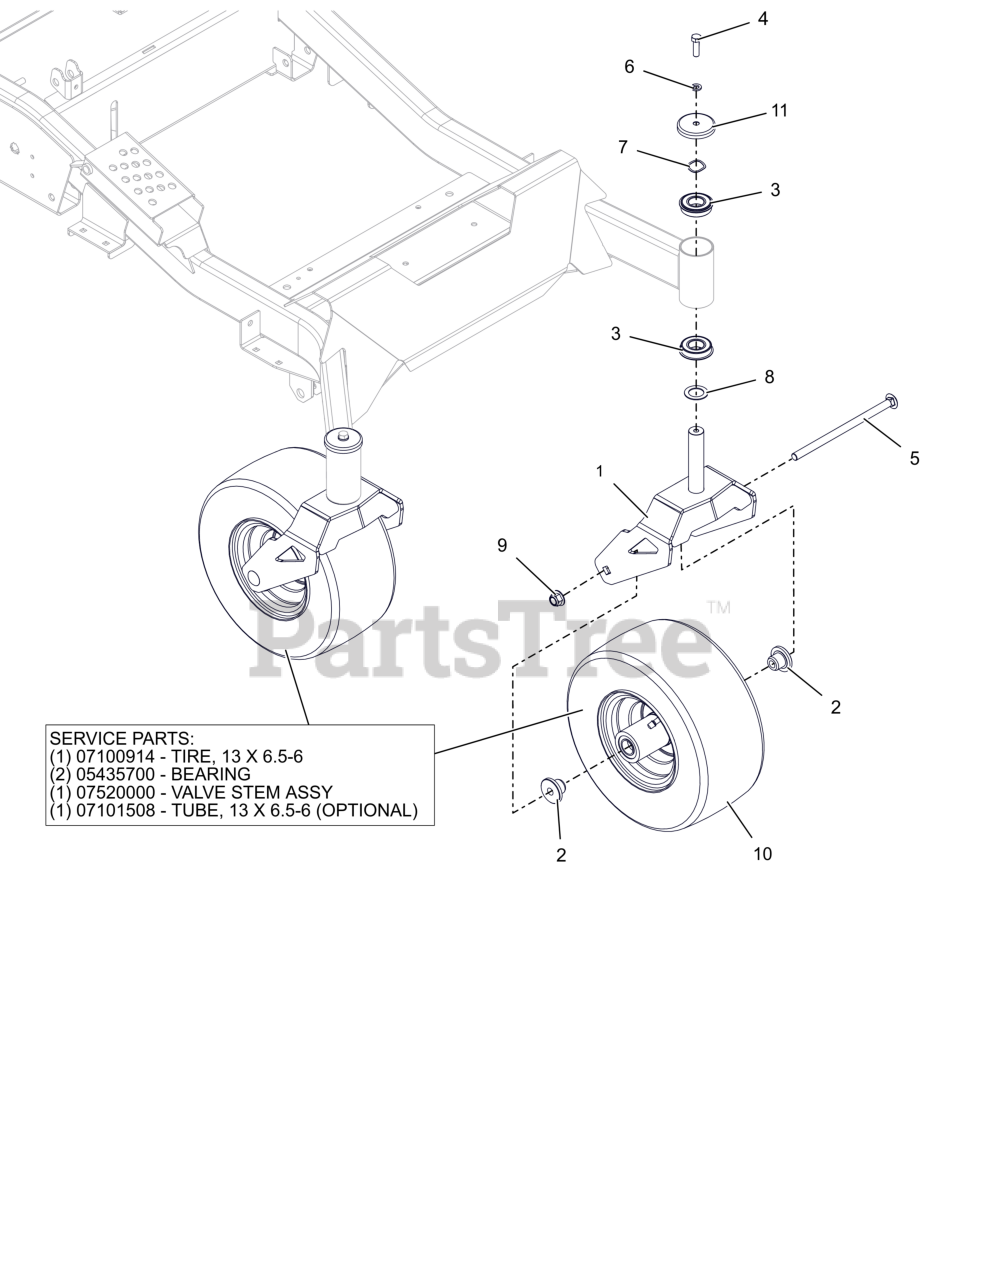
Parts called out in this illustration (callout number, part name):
1	WLDMT, CASTER FORK-HD (ORANGE)
2	SPACER, FRONT WHEEL
3	BEARING, BALL -2.000 OD X 1.000 ID X .5625 W/RING
4	BLT- HEX .38-16X1.25 G5 ZB500
5	BLT-RHSN .50-13X9.00 G5 ZCC NS
6	WSHR-LK-REG .375X.094 ZB500
7	WSHR-WAVE 1.0X1.25X.028 .145FH
8	WSHR-HRD-THRS 1.007X1.542X.062
9	NUT,NYL-FLG .50-13 GF ZCC
10	ASM, TIRE/WHEEL 13 X 6.50-6 BLK RIM
10	LAWN TIRE FRONT, 13X6.50-6 SMOOTH
10	BRG, 25MM ID X 52MM OD X 15MM
10	VALVE STEM ASS'Y
10	TIRE TUBE, 13/6.5-6 4 PLY TR87 90 BENT VALVE
11	SHIELD, AXLE BEARING
